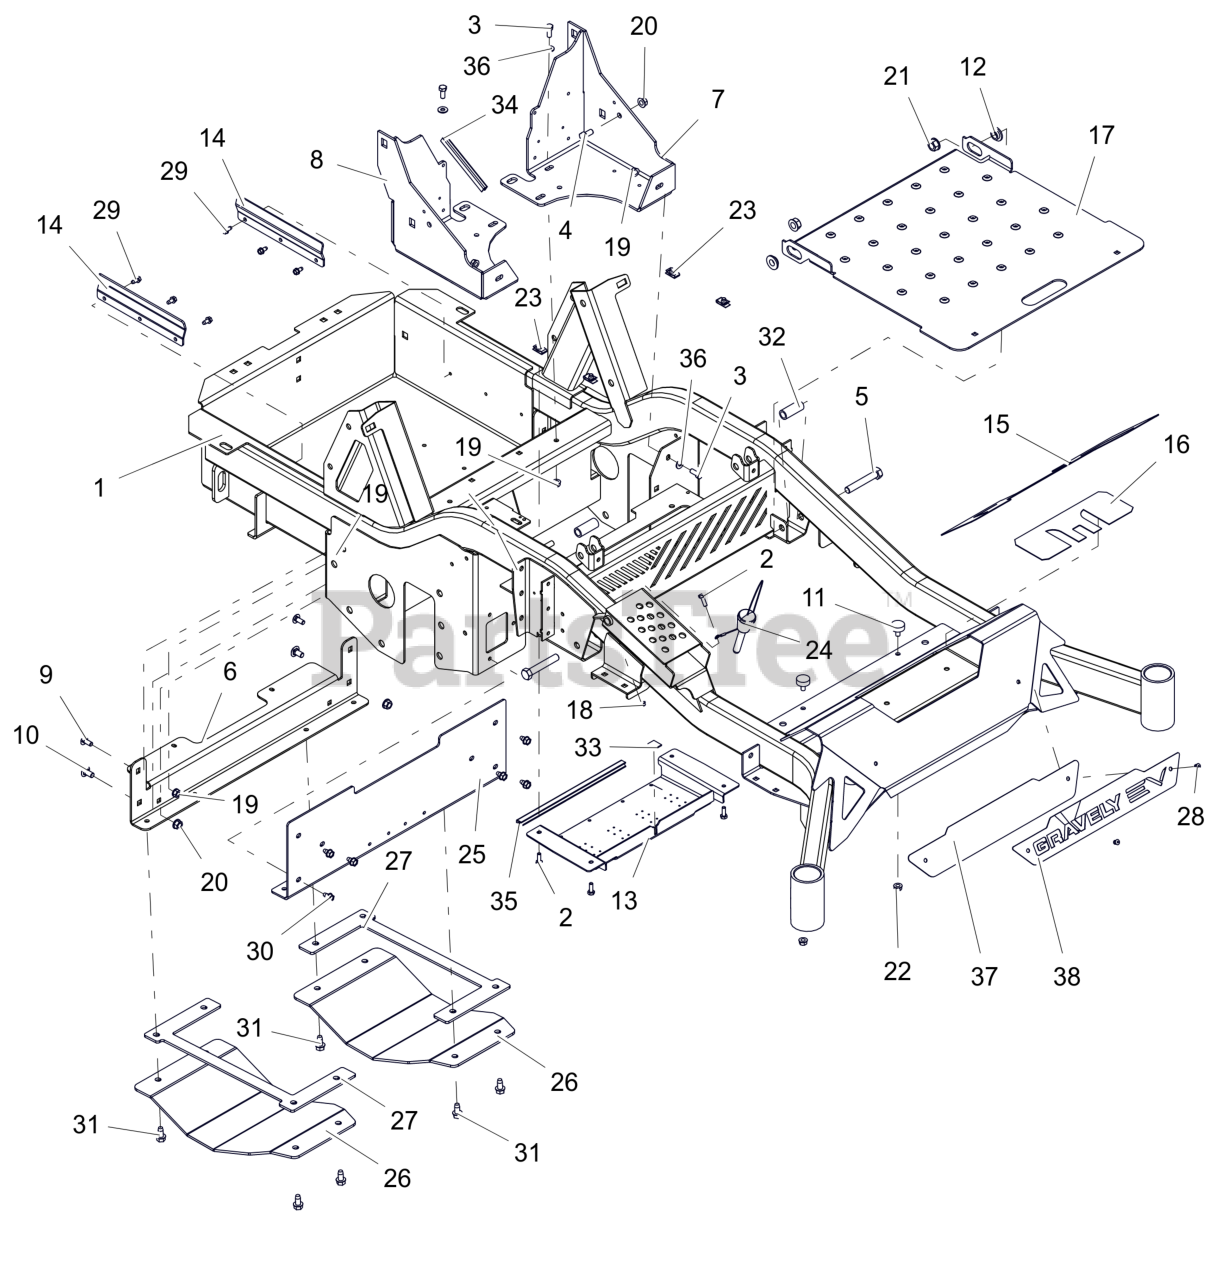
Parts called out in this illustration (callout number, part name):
1	KIT,EV FRAME(LG)W/DECALS-G
2	BLT, HEX .25-20X.75 G5 ZCC
3	BLT,HEX .31-18X.75 G5 ZCC
4	BLT,HEX .38-16X.75 G5 ZCC
5	BLT, HEX .50-13X3.00 G5 ZCC
6	BRKT, SKID PLATE MTG. (RED)
7	BRKT, SUPPORT ROPS -LH (RED)
8	BRKT, SUPPORT ROPS-RH (RED)
9	BLT, RHSSN.31-18X.750 G5 ZCC
10	BLT, RHSSN .38-16X.75 G5 ZCC
11	BUMPER, RUBBER
12	BSHG-FLG .515X.750X.310X1.120
13	COVER, BOTTOM ACCESS -OPEN (RED)
14	DEFLECTOR, BATTERY -EV (RED)
15	GRIP, FRONT
16	GRIP, TAPE FRONT
17	KIT,ACCESS PANEL W/DECALS-RED
18	NUT-LK-CTR-FLG .25-20 ZC120
19	NUT,LK-CTR-FLG .31-18 GF ZCC
20	NUT-LK-CTR-FLG .375-16 GF ZCC
21	NUT-LK-CTR-FLG .500-13 GG ZCC
22	NUT,SPNLK-FLG .31-18 G5 ZCC
23	NUT-RTNR .25-20X.56
24	PIN, MAGNETIC .50X2.50
25	PLATE, FRONT FRAME (RED)
26	PLATE, SKID (BLACK)
27	PLATE, SKID TENSION (BLACK)
28	RIVET, .1875 AL/AL .126-.250
29	SCR-TAP .25-20X.50 HWH ZCC
30	SCR,TAP .312-18X.50 HWH TR ZCC
31	SCR,TAP .375-16X.75 HWH TR ZCC
32	SPACER, .515X.75X1.83
34	STRIP, COWL
35	STRIP, COWL
36	WSHR, FLT .312X.734X.065 ZCC
37	PLATE, BACK - GRAVELY (BLACK)
38	PLATE, LOGO - GRAVELY EV (RED)
